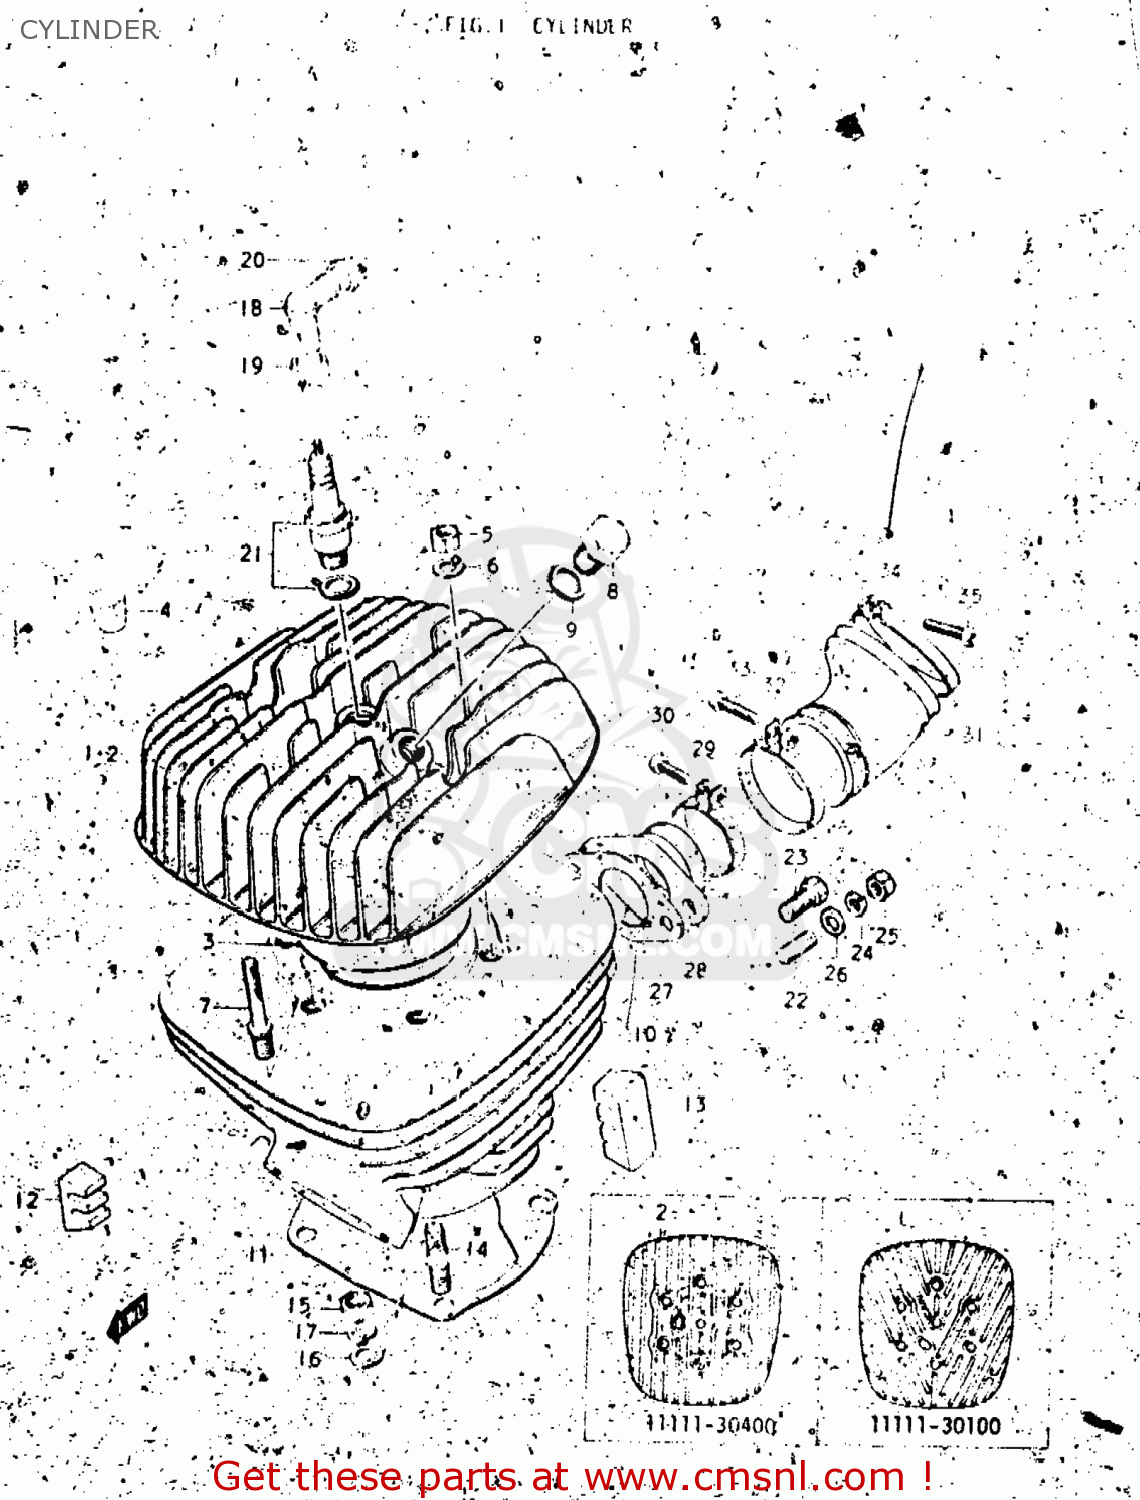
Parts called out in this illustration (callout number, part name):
1	HEAD,CYLINDER
2	HEAD,CYLINDER
3	GASKET,CYLINDER HEAD (NAS)
4	PAD,CYLINDER HEAD
5	NUT (8MM)
6	WASHER
7	BOLT,STUD
8	PLUG
9	GASKET(14X19.2X2) (NAS)
10	CYLINDER
11	GASKET,CYLINDER (MCA)
12	PAD,CYLINDER
13	PAD,CYLINDER
14	STUD 10X30
15	NUT
16	WASHER
17	LOCK WASHER
18	CAP,SPARK PLUG
19	SEAL,SPARK PLUG
20	SEAL,HIGH TENSION CORD
21	SPARK PLUG
22	STUD BOLT
23	BOLT
24	LOCK WASHER
25	NUT
26	WASHER
27	GASKET,CARBURETOR (NAS)
28	PIPE,INTAKE
29	CLAMP
30	SCREW
31	TUBE,AIR CLEANER OUTLET
32	CLAMP J,K,L,M; FROM 09402-00092
33	SCREW
34	CLAMP
35	SCREW
